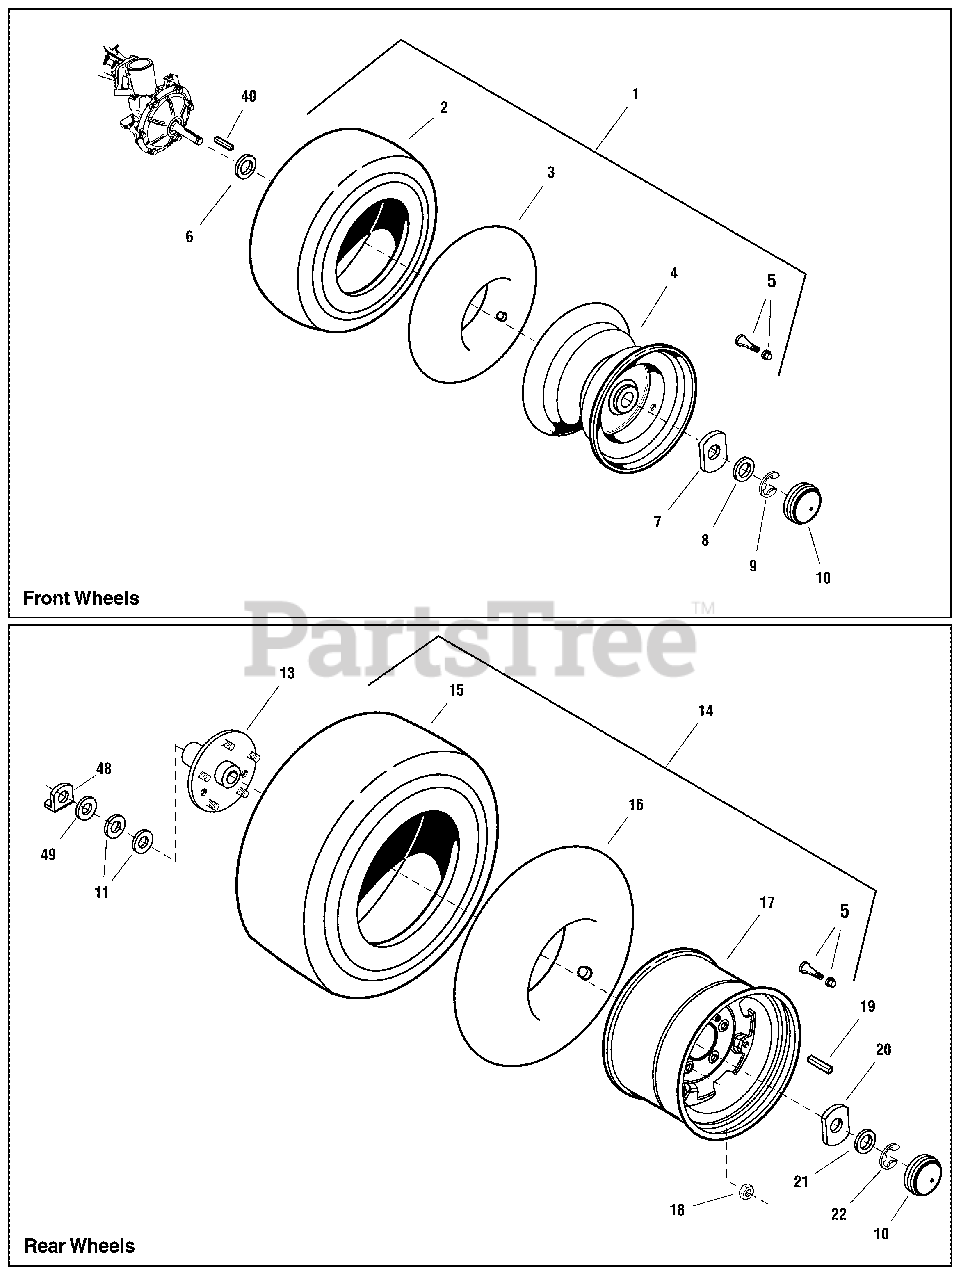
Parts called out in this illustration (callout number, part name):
1	WHEEL & TIRE ASSEMBLY, 16X6.5-8, Front
2	TIRE, 16X6.5-8
3	TUBE, Tire
4	RIM, Wheel Assembly
5	VALVE STEM & CAP ASSEMBLY
6	WASHER, Flat 3/4 x 1-5/8 x 1/8
7	WASHER, Flat
8	WASHER, 3/4
9	RING
10	CAP, Hub
11	WASHER, 1 x 2-1/4 x 1/8
13	PLATE & HUB ASSEMBLY
14	WHEEL & TIRE ASSEMBLY, 23X10.5-12, Rear
15	TIRE, 23X10.5-12
16	TUBE, Tire
17	WHEEL
18	NUT, Hex, 7/16-20
19	KEY, Hi-Pro 1/4 x 2
20	WASHER, Flat
21	WASHER, Flat
22	RING
40	KEY, Parallel, 3/16 x 3/16 x 1-1/2
48	WASHER, Axle Seal
49	WASHER, 1
